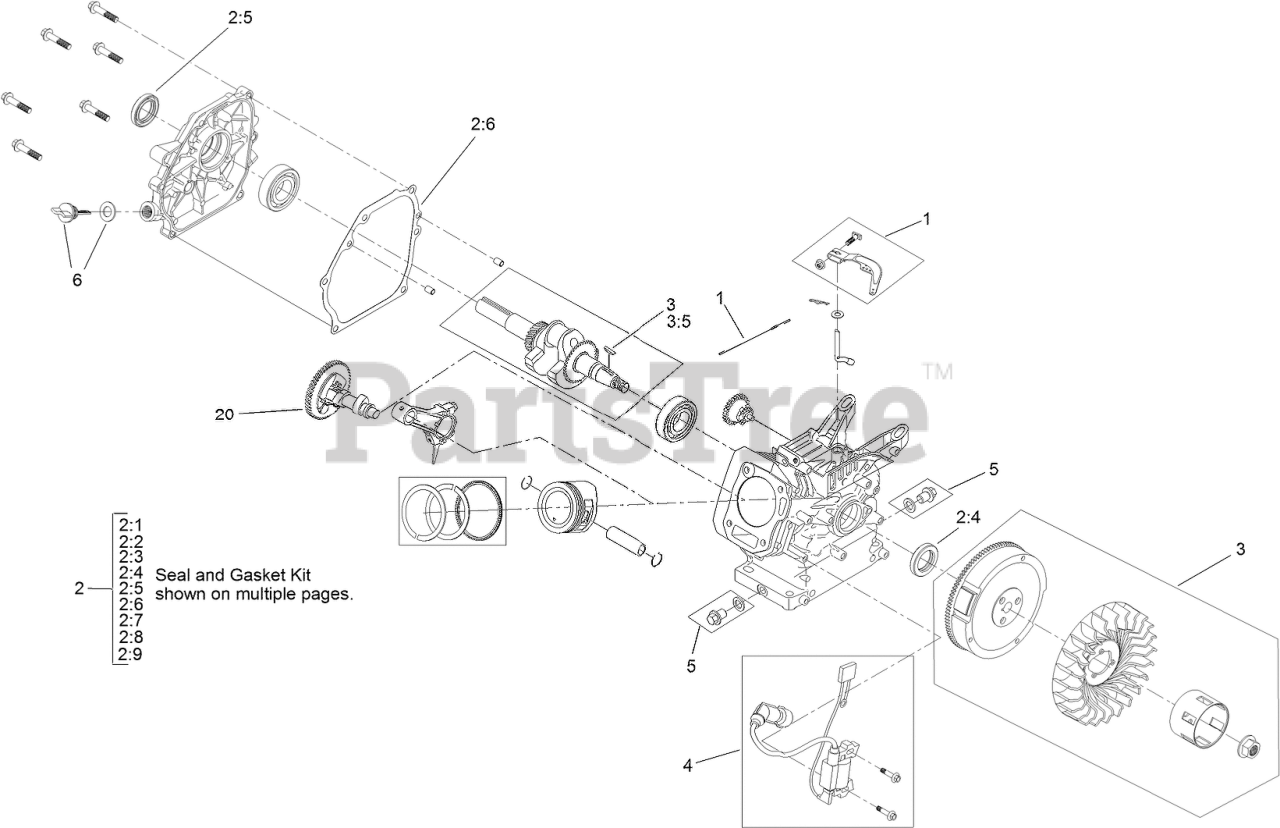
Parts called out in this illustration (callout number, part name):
1	GOVERNOR KIT
2	GASKET AND SEAL KIT
2:1	GASKET-COVER, VALVE
2:2	GASKET-EXHAUST
2:3	GASKET-HEAD, CYLINDER
2:4	SEAL-OIL
2:5	SEAL-OIL
2:6	GASKET-COVER, CRANKCASE
2:7	GASKET-CARBURETOR
2:8	GASKET-CARBURETOR
2:9	GASKET-CARBURETOR
3	FLYWHEEL KIT
3:5	KEY-WOODRUFF
4	IGNITION KIT
5	DRAIN PLUG KIT
6	DIPSTICK AND O-RING KIT
20	CAMSHAFT
